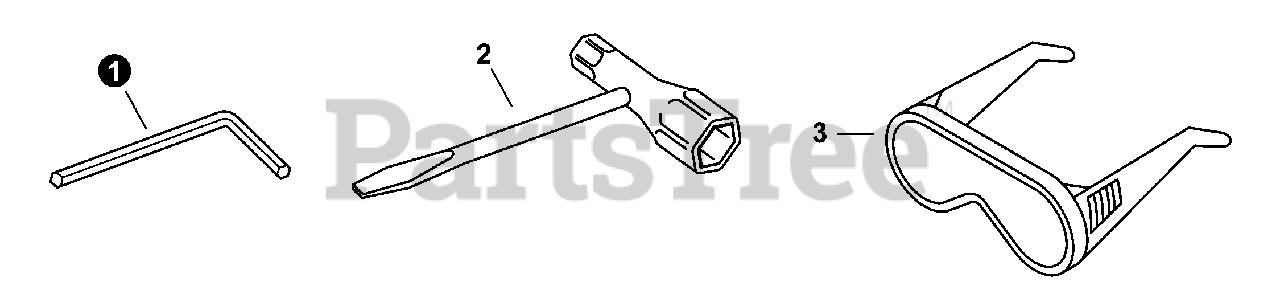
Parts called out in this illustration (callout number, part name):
1	WRENCH, ALLEN 4MM
2	T-WRENCH 13×19 L= 180
3	GLASSES, SAFETY
